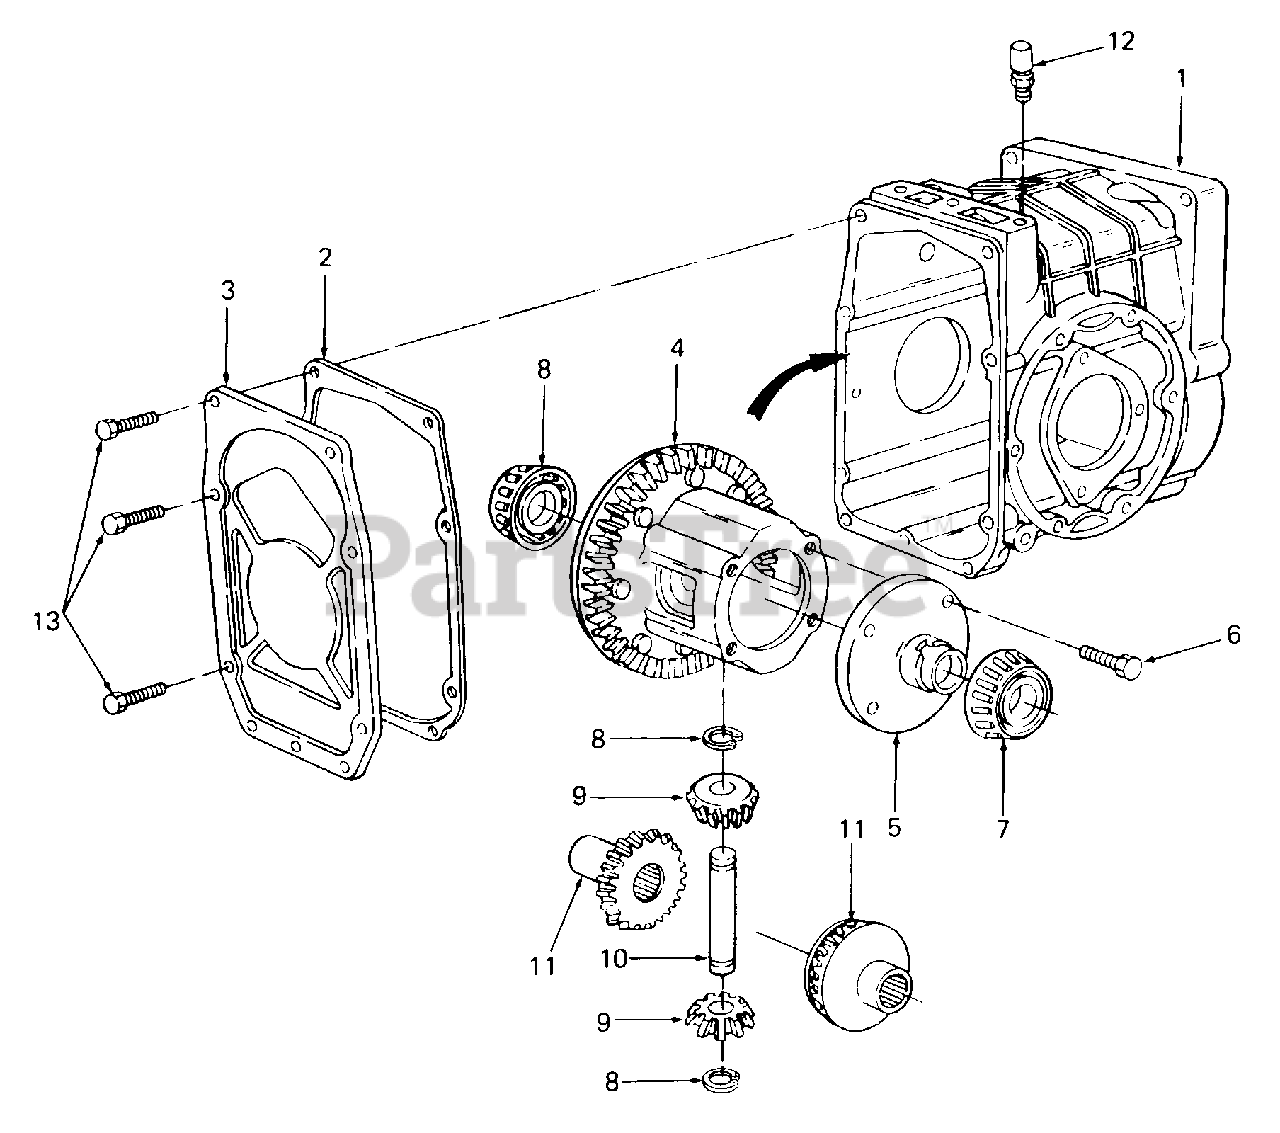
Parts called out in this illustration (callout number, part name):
1	Housing Assy, Rear Axle
2	Gasket, Rear Cover
3	Plate, Rear Cover
4	Gear Assy, Ring w/Case
5	Plate, Differential Flange
6	Bolt, Hex Patch, 5/16-18 X 1.0 Lg GR5
7	Cone, Roller Brg
8	Ring, Retaining
9	Gear, Pinion - 1OT
10	Shaft, Cross
11	Gear, Side - 16T
12	Breather, Housing
13	Bolt, Hex Patch, 3/8-16 X .62 Lg GR5
